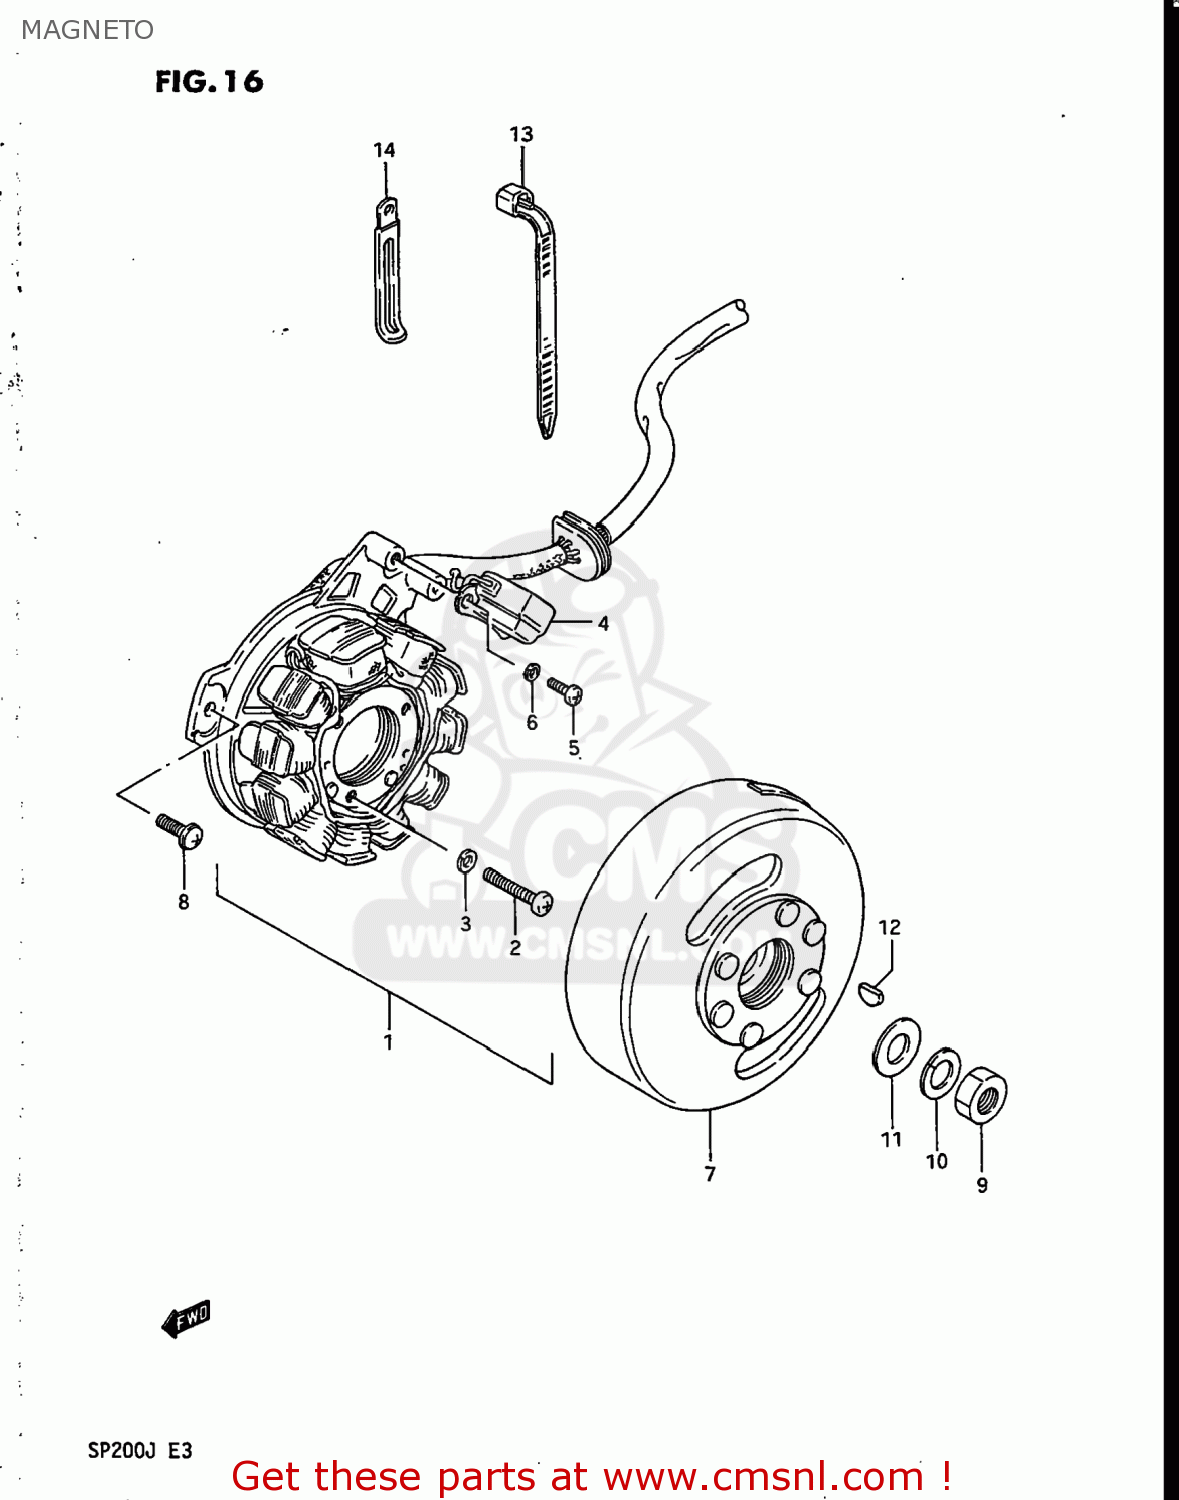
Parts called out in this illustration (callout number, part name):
1	STATOR ASSEMBLY
2	SCREW
3	LOCK WASHER
4	COIL,PICK UP
5	SCREW
6	WASHER,LOCK 4M
7	ROTOR
8	SCREW(5X14)
9	NUT (10MM)
10	WASHER,LOCK,10
11	WASHER
12	KEY
13	CLAMP(L:125)
14	CLAMP
